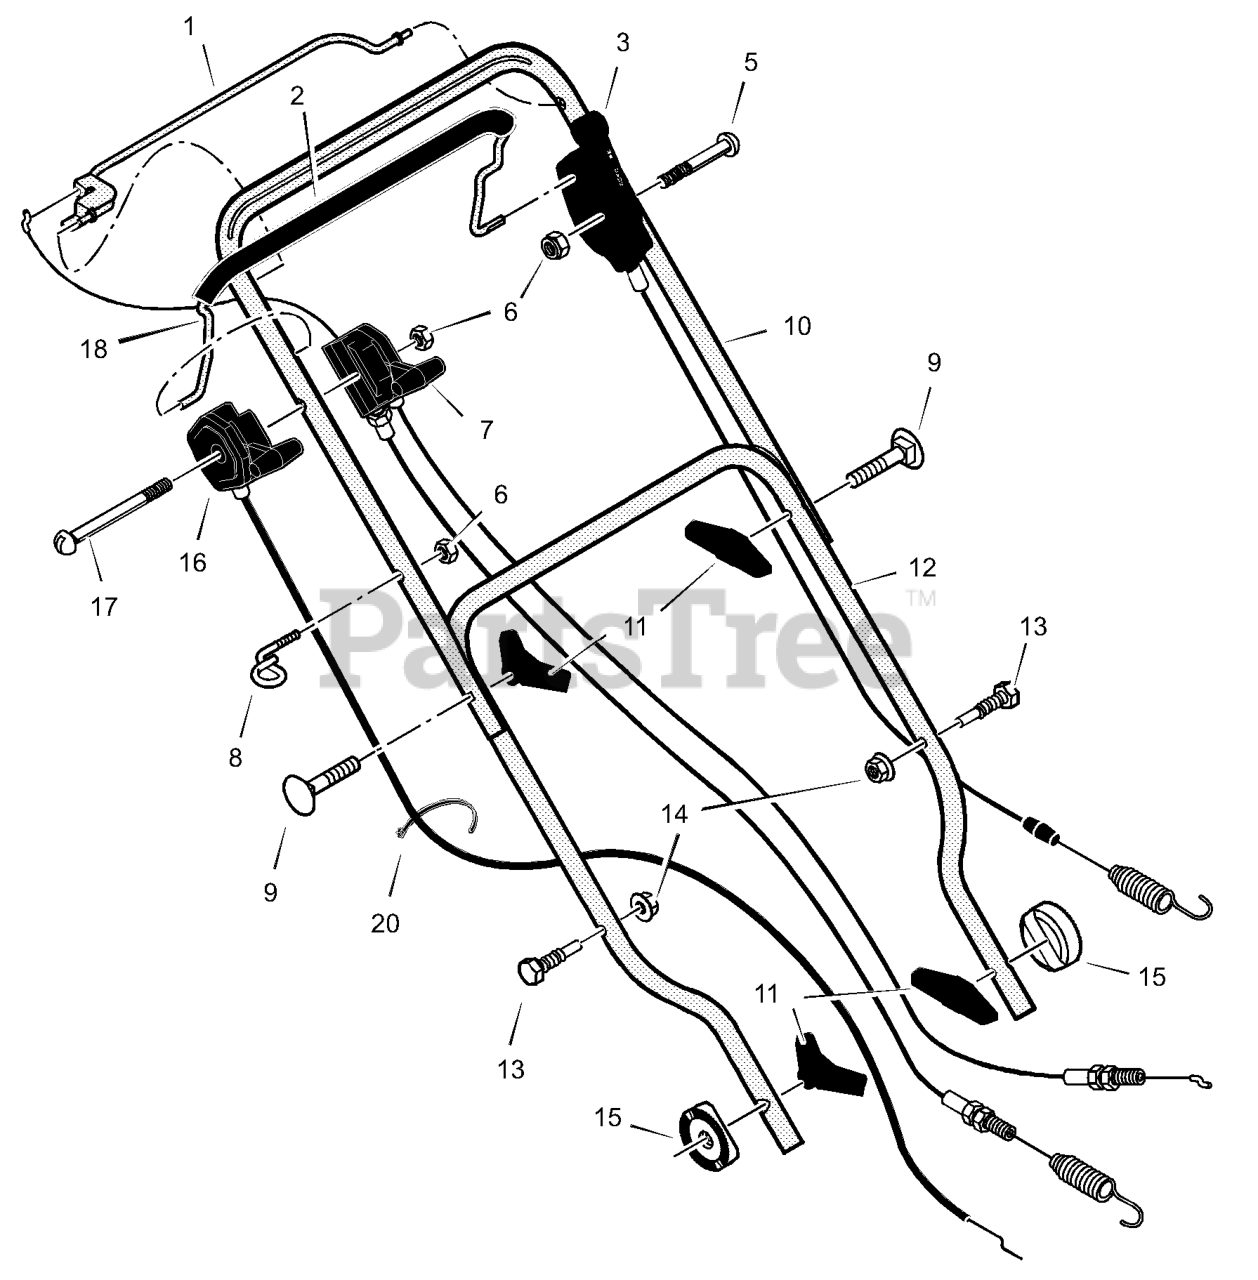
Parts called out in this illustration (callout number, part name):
1	Lever, Drive
2	Cover, Stop Lever
3	Control, Blade
6	Nut
7	Control, Speed & Drive Cable
8	Guide, Rope
9	Bolt, Carriage
10	Handle, Upper
11	Knob, Handle
12	Handle, Lower
13	Bolt, Handle Support
14	Nut, Flange
15	Adjuster, Handle
16	Cable and Throttle Control
17	Bolt, Hex
18	Lever, Blade Stop
20	Tie, Cable
